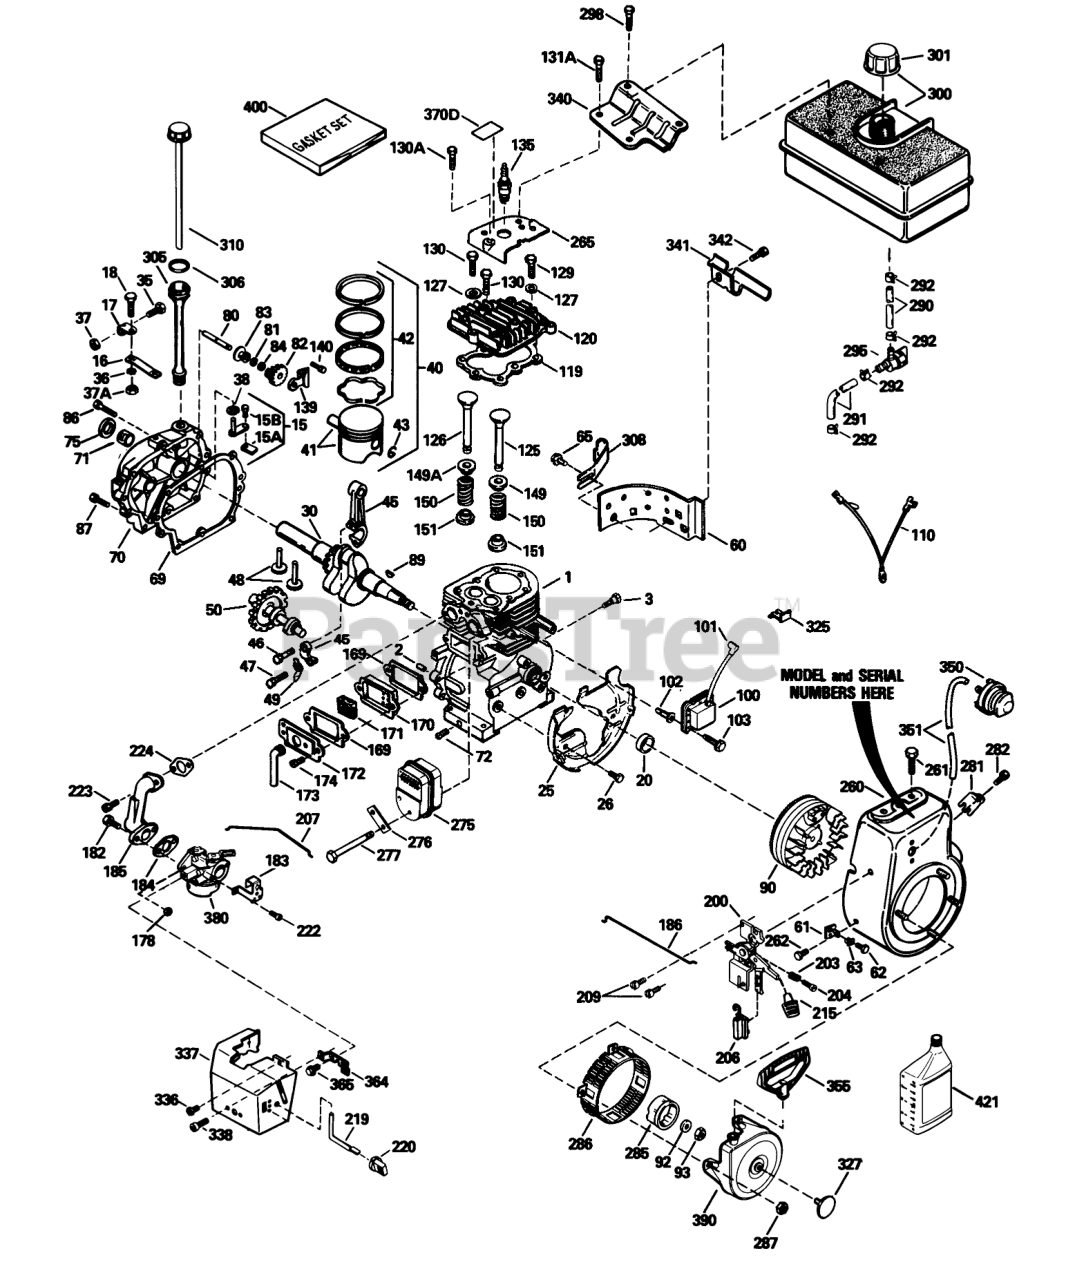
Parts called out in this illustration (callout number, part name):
1	Cylinder (Incl. Ref. #2, 20, & 72)
2	Pin-Dowel
3	Screw (1/4-20x1/2)
15	Rod Ass-y-Governor (Incl. Ref. #15A & 15B)
15A	Yoke-Governor
15B	Screw (6-40x5/16)
16	Lever-Governor
17	Clamp-Lever, Governor
18	Screw
20	Seal-Oil
25	Baffle-Blower Housing
26	Screw (1/4-20x19/32)
30	Crankshaft
36	Washer-Lock
37	Nut-Lock
37A	Nut-Lock
38	Ring-Retaining
40	Piston-Pin & Ring Ass-y Std. (Incl. Ref. #41, 42, & 43)
40	Piston-Pin & Ring Ass-y (.010 Oversize) (Incl. Ref. #41, 42, & 43)
40	Piston-Pin & Ring Ass-y (.020 Oversize) (Incl. Ref. #42, 42, & 43)
41	Piston & Pin Ass-y (Std.) (Incl. Ref. #43)
41	Piston & Pin Ass-y (.010 Oversize) (Incl. Ref. #43)
41	Piston & Pin Ass-y (.020 Oversize) (Incl. Ref. #43)
42	Ring Set (Std.)
42	Ring Set (.010" OS)
42	Ring Set (.020" OS)
43	Ring-Retaining, Piston Pin
45	Rod Ass-y-Connecting (Incl. Ref. #46, 47, & 49)
46	Bolt-Rod
47	Bolt-Rod
48	Lifter-Valve
49	Dipper-Oil
50	Camshaft (MCR)
60	Extension-Housing, Blower
61	Bracket
62	Screw (8-32 x 3/8)
63	Grommet
69	Cylinder Cover Gasket
70	Cover Ass-y-Cylinder (Incl. Ref. #75 & 80)
71	Bushing-Crankshaft
72	Plug-Drain, Oil (SQH 1/4-18)
75	Seal-Oil
80	Shaft-Governor
81	Washer-Flat
82	Gear-Governor (Incl. Ref. #81)
83	Spool-Governor
84	Ring-Retaining
86	Screw (1/4-20x1-3/16)
87	Screw (1/4-20x1-11/16)
89	Key-Flywheel
90	Flywheel (W/Ring Gear)
92	Washer-Belleville
93	Nut-Flywheel
100	Solid State ASM
101	Cover-Spark Plug
102	Stud
103	Screw
110	Ground Wire
119	Gasket-Cylinder Head
120	Head Cylinder
125	Valve-Exhaust (Std.) (Incl. Ref. #151)
125	Valve-Exhaust (1/32" Overrsize) (Incl. Ref. #151)
126	Valve-Intake (Std.) (Incl. Ref. No. 151)
126	Valve-Intake (1/32" Oversize) (Incl Ref. #151)
127	Washer-Flat
129	Screw (5/16-18x1-25/32)
130	Screw (5/16-18x1-1/2)
130A	Screw (1/2-20x5/8)
131A	Screw
135	Spark Plug-Resistor (R J19 L M)
139	Bracket-Gear, Governor
140	Screw (10-24x1/2)
149	Cap-Spring, Valve
149A	Cap-Spring, Valve
150	Spring-Valve
151	Keeper-Spring, Valve
169	Gasket-Cover, Valve
170	Body-Breather
171	Element-Breather
172	Cover-Valve
173	Tube-Breather
178	Nut and Lock Washer (1/4-28)
182	Screw (1/4-28x1)
183	Bracket-Choke
184	Gasket-Carburetor To Intake Pipe
185	Pipe-Intake
186	Link-Governor
200	Bracket Ass-y-Control (Incl. Ref. #19, 203, 204, & 206)
203	Spring-Compression
204	Screw
206	Terminal
207	Link-Throttle
209	Screw (10-32 x 1/2)
215	Knob-Control
219	Rod-Choke
220	Knob-Control
222	Screw (10-32 x 1/2)
223	Screw (T-30, 5/16-18x1-3/32)
224	Gasket-Pipe, Intake
260	Housing-Blower
261	Screw (5/16-18x3/4)
265	Cover-Cylinder Head
275	Muffler
276	Plate-Locking
277	Screw
282	Screw (8-32 x 3/8)
285	Hub-Starter
286	Screen-Starter
287	Nut and Lock Washer (1/4-28)
290	Line-Fuel (8.62)
291	Line-Fuel
292	Clamp-Line, Fuel
295	Valve-Shut Off, Fuel
298	Screw (1/4-15x7/8)
300	Tank-Fuel (Incl. Ref. #292 & 301)
301	Cap-Fuel
305	Tube-Fill, Oil
308	Clip-Tube, Fill
310	Gauge Oil ASM
325	Clip-Wire
327	Plug Starter
336	Screw (10-32x1/2)
337	Cover-Carburetor
338	Screw (10-32 x 3/8)
340	Bracket-Tank, Fuel
341	Bracket-Tank, Fuel (Black)
342	Screw (1/4-20x19/32)
350	Primer-Asm
351	Line-Primer
355	Handle-Starter, Mitten Grip
364	Bracket-Carburetor
365	Screw (8-32x27/64)
380	Carburetor (Incl. Ref. #184)
390	Rewind Starter
400	Gasket Set
421	Oil-Engine (SAE 5W30)
